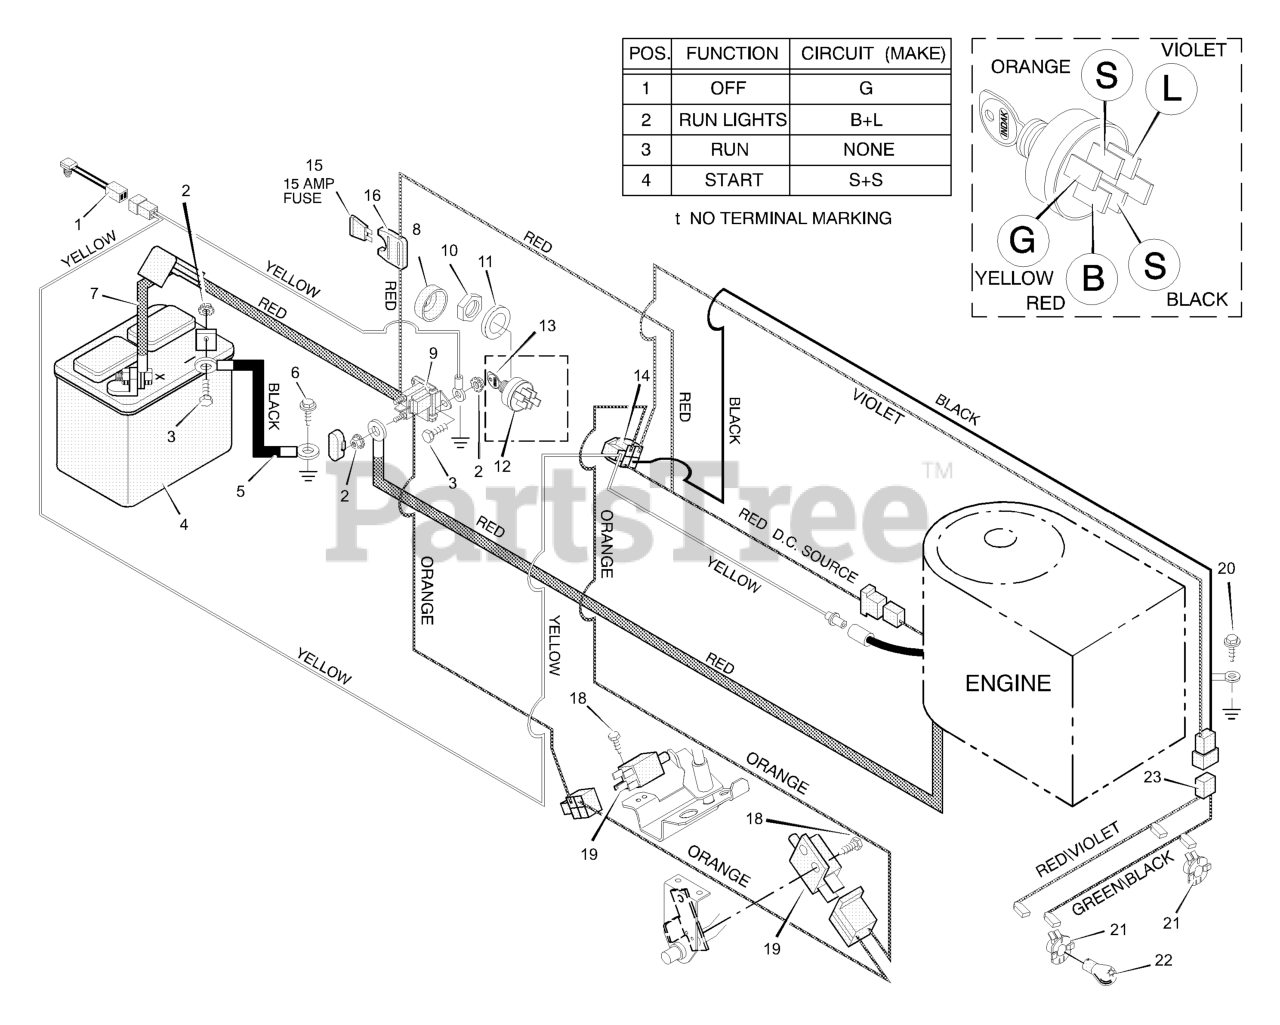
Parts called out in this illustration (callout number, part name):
1	Switch, Seat Sensor
2	Locknut
3	Bolt, Hex
4	Battery
5	Cable, Battery Ground
7	Cable, Red Battery
8	Cap, Ignition
9	Solenoid
10	Nut
12	Switch, Ignition
13	Key, Ignition
14	Harness, Chassis Wire
16	Holder, Fuse
19	Switch, Clutch
20	Screw
21	Socket, Light
22	Bulb, Light
23	Harness, Light Wire
24	Cover, Terminal
